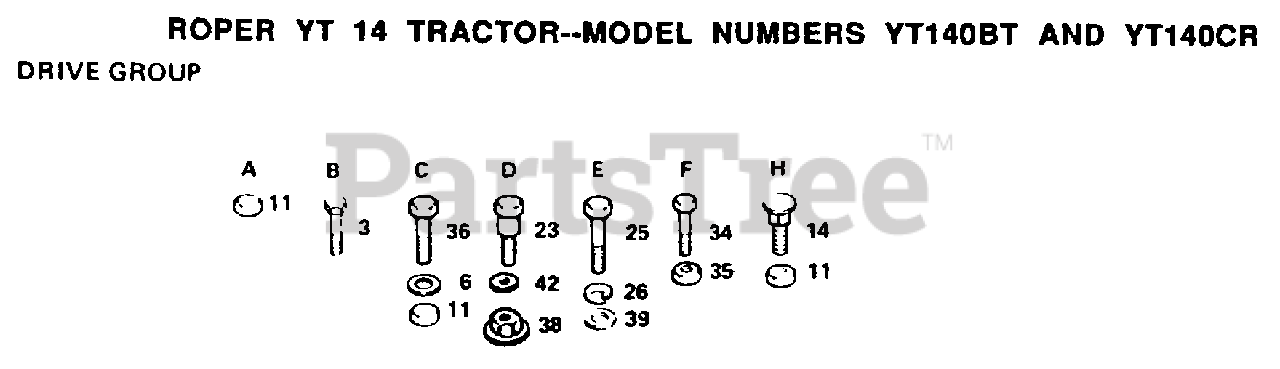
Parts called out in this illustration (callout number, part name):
3	SCREW
6	WASHER
14	BOLT
23	"BOLT, SHOULDER LT"
26	LOCKWASHER
34	BOLT
36	BOLT
38	NUT SPECIAL T
39	WASHER T
42	WASHER T
